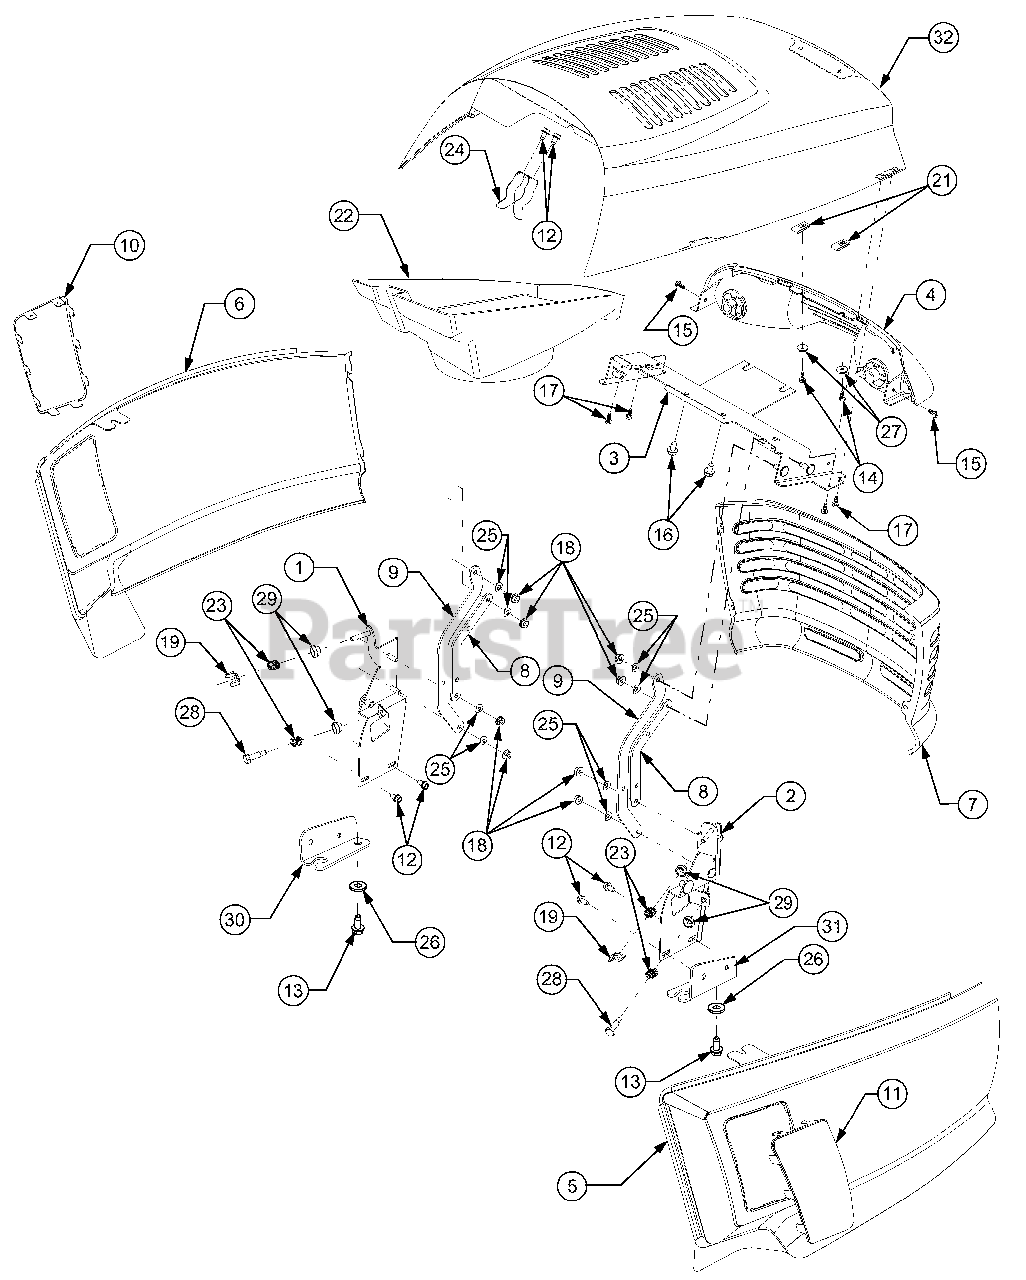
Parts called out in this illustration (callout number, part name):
1	Bracket Assembly, Grille LH
2	Bracket Assembly, Grille RH
9	Link, Hood, Rear
13	Screw, Hx Wash. Hd Tapp, 5/16-18 x .75
14	Screw, Hx Tapp, 10-16 x .625
15	Screw, Hx Wash. Hd Tapp, 10-16 x .5
16	Screw, Hx Wash. Hd Tapp, 5/16-12 x .75
17	Screw, Truss Phillips Tapp, 10-16 x .5
18	Nut, Flange Lock, 1/4-20
19	Nut, Wing, 1/4-20
21	Nut, Speed, 10z U-type
22	Plenum, Hood
23	Spring, Compression, .50 OD x .5 Lg
24	Spring, Latch, Hood
25	Washer, Spring, .265 x.562 x.025
26	Washer, Flat, .385 x 1.0 x .135
27	Washer, Flat, .194 x .62 OD x .063
28	Screw, Shoulder, .31x .75, 1/4-20
29	Bushing, Tapered, .32 ID x .69 OD
